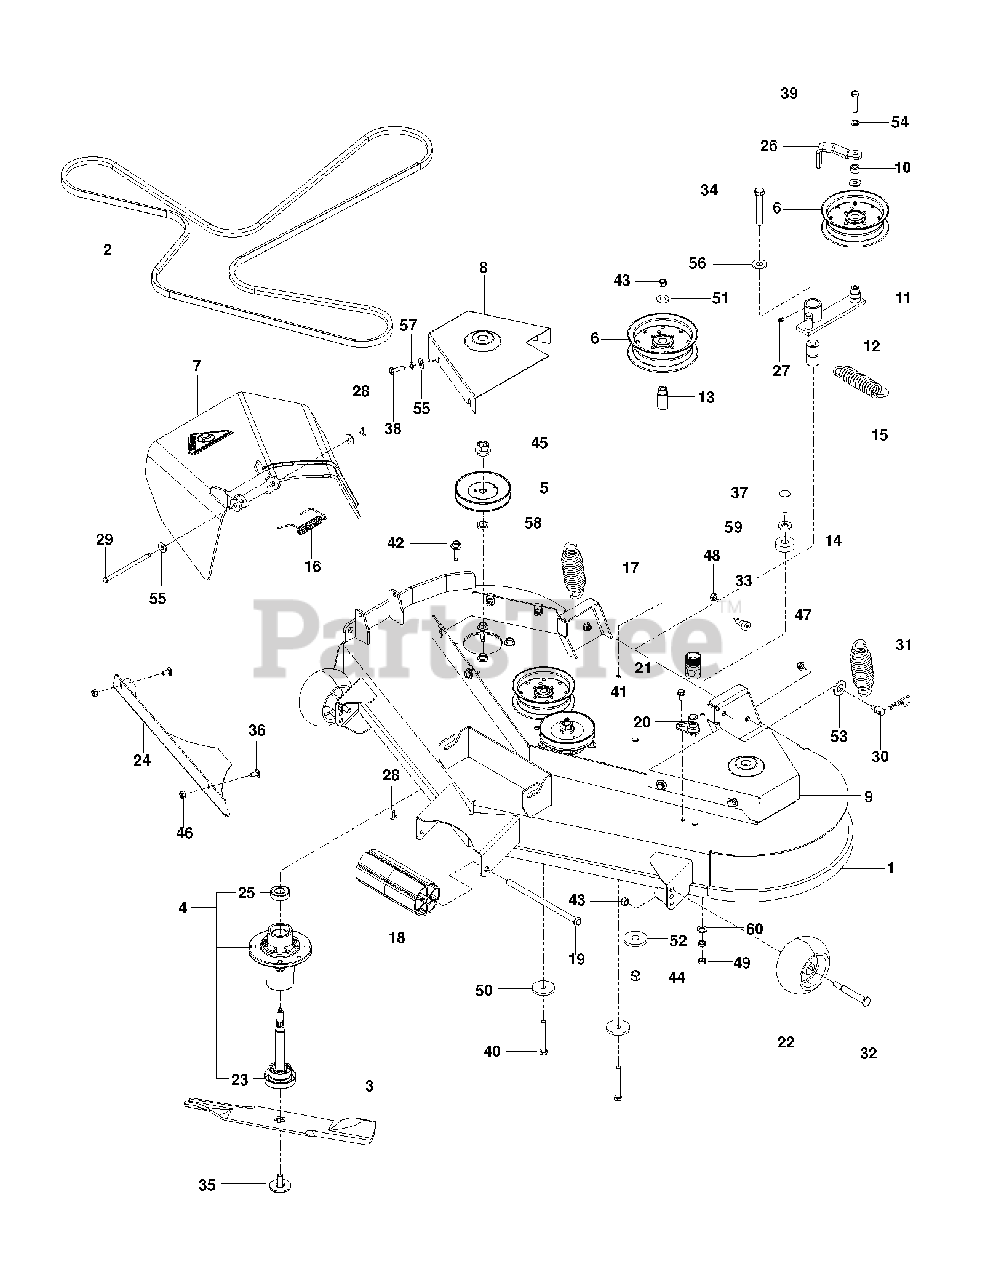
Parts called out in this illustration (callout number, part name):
2	BELT, DECK
3	BLADE, 16-1/4"
4	MANDREL ASM, CAST IRON
5	PULLEY MANDREL
6	PULLEY, IDLER
7	DISCHARGE CHUTE 48"
8	SHIELD.BELT.RHSX428
9	ROLLER MOUNT - CENTER
11	IDLER ARM
12	PIVOT BUSHING
13	IDLER BUSHING
14	ISO-MOUNT BUSHING
16	SPRING - TORSION
17	SPRING
18	NOSE ROLLER 48"
19	ROD.ROLLER.NOSE.NARROW.48"
20	PORT.WASHOUT
21	COUPLING.QUICK CONNECT
22	WHEEL GAGE DONUT
23	SHAFT ASM MANDREL
24	CONFINEMENT PLATE 48" BLK
26	GUIDE, BELT
27	ZERK
28	COTTER PIN
29	PIN-CLEVIS 5/16 DIA X 5.19 ZD
30	STUD.FASTNER.W/ANTI-ROTATE
31	HAIRPIN #4
32	BOLT.SHOULDER.3/8-16X3-5/8
33	SB 3/8-16 X 3/8 SKT HD ZD
34	Hex Capscrew, 1/2-13 X 3-1/4 Gd 5 Zd
35	BOLT.WASHER.ASM.7/16-2
36	BOLT
37	RHSNB 3/8-16X1-3/4
39	HCS 3/8-16 X 1 3/4 GR5
40	BOLT
41	SCREW
42	Hex Washer Head Bolt, .313-18 X 1.19
43	NUT
44	NUT
45	NUT.FLANGE.LOCK.TOP
46	NUT.71038.31-18.HEX.NYLOCK
47	5/16-18 NYLOC FLANGE NUT
48	NUT HEX 3/8-16 NYLON, THIN
49	NUT
50	SPINDLE WASHER
51	WASHER 3/8 FLAT
52	WASHER, SUPPORT
54	LOCKWASHER
55	WASHER
56	WASHER 1/2 FLAT
57	Lock Washer, 5/16
58	WASHER.SPACER.MANDREL
59	WASHER STEEL
